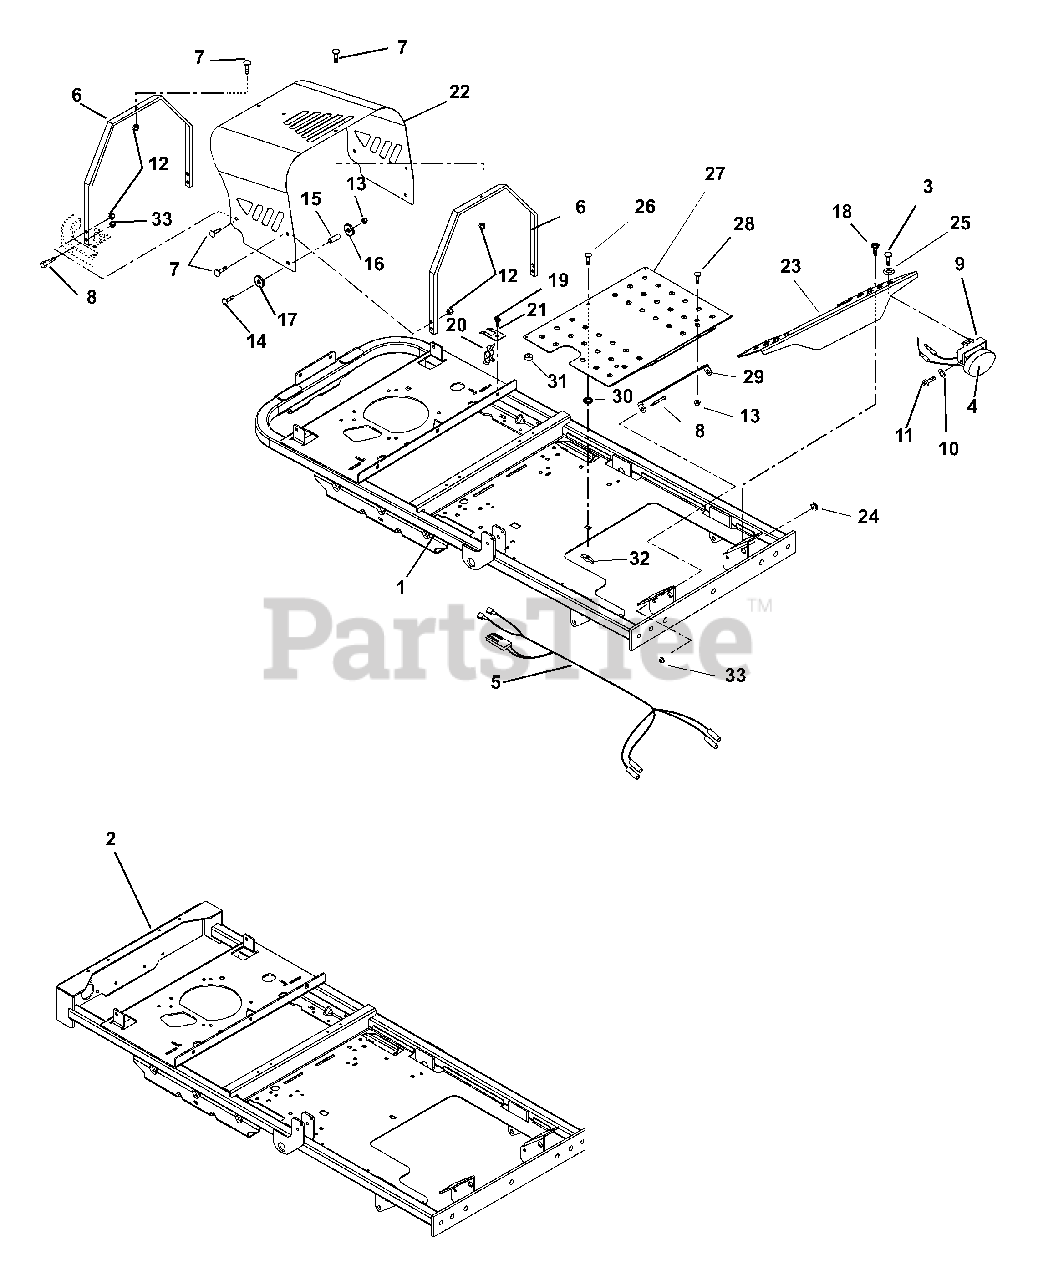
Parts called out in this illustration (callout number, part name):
1	WMT, PIVOTING AXLE FRAME
2	WMT, FRAME (CE PIVOTING)
3	SCR-CAP BTHD.31-18X.50 GR5 YZ
4	LIGHT-CONS RIDE ON- SEE B-2124
5	HARNESS, LIGHT
6	BRACE, HOOD
7	@BLT-RHDSSQNK .31-18X.62 G5YZ
8	BOLT-SHLDR .375-16X.150
9	WMT, LIGHT BRACKET
10	WSHR-LK 4MMX1MM REG CL ZINC
11	SCREW-M4X.07X8 SHCS CLZNC
12	@NUT-LK-TOP-FLG .31-18 YWZC
13	@NUT-LK-NYL-FLG .38-16 YWZC
14	@BLT-RDHDSQNK .38-16X2.00 G2YZ
15	BSHG, SPCR .390X.625X1.25 PM
16	WSHR-FL-STL .375X1.125X.065YWZ
17	@WSHR-FL-STL.531X1.06X.095YWZC
18	@SCR-TAP .31-18X.50 HWH TR YWZ
19	@SCR-TAP .25-20X.50 HWH TR YWZ
20	HOOD CLIP
21	BRACKET, HOOD CLIP
22	ENGINE HOOD, CE ZOOM
23	FOOTREST
24	GROMMET, RUBBER 3/8 I.D.
25	@WSHR-LK .31X.078 REG YWZC
26	@BLT-RDHDSQNK .31-18X1.00 G5YZ
27	PLATE, DECK ACCESS
28	@BLT-RDHDSQNK .38-16X1.00 G5YZ
29	BRACKET, DECK ACCESS
30	NUT-PUSH .312
31	BUMPER GROMMET
32	KNOB - WING .312-18 UNC
33	@NUT-LK-TOP-FLG .38-16 YWZC
